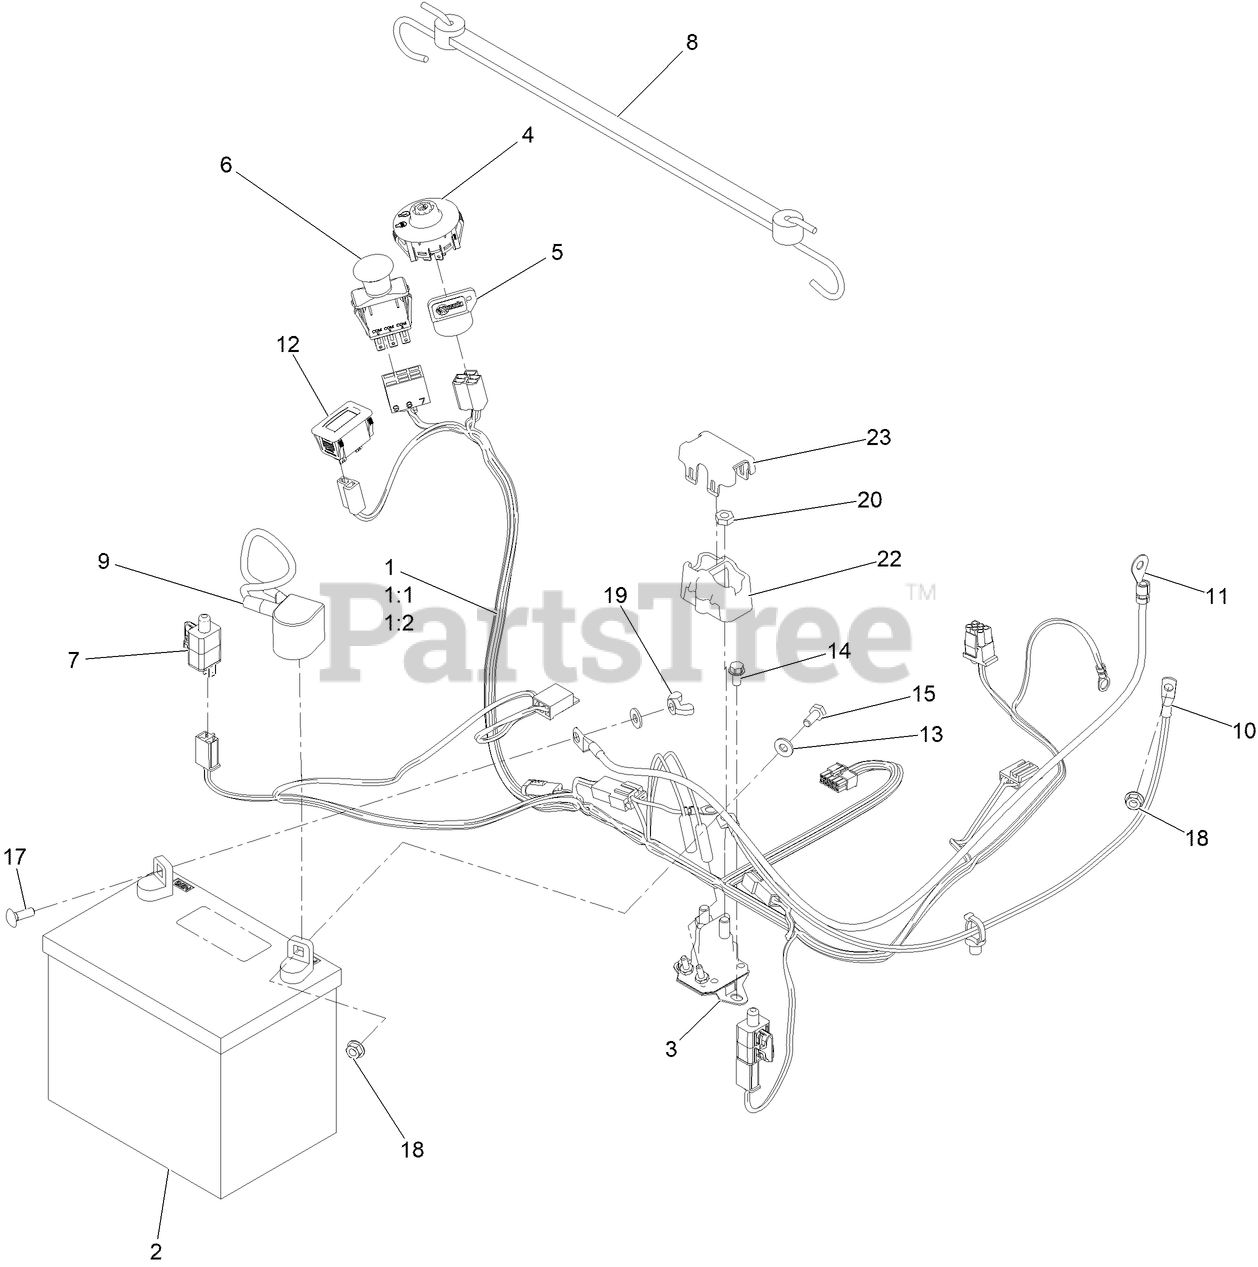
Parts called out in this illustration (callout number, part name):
1	HARNESS-WIRE
1:1	FUSE-BLADE, 15 AMP
1:2	FUSE-BLADE, 25 AMP
2	BATTERY
3	SOLENOID
4	SWITCH-IGNITION
5	KEY-IGNITION
6	SWITCH-PTO
8	STRAP-RUBBER
9	CABLE-BATTERY, POS
10	CABLE-BATTERY, RED (8 GAUGE)
11	CABLE-BATTERY, BLACK
12	HOURMETER
13	WASHER-FLAT
14	SCREW-HWH
15	SCREW-HH
17	BOLT-CARR
19	NUT-WING
20	NUT-JAM
22	COVER-SOLENOID
23	CAP-SOLENOID
